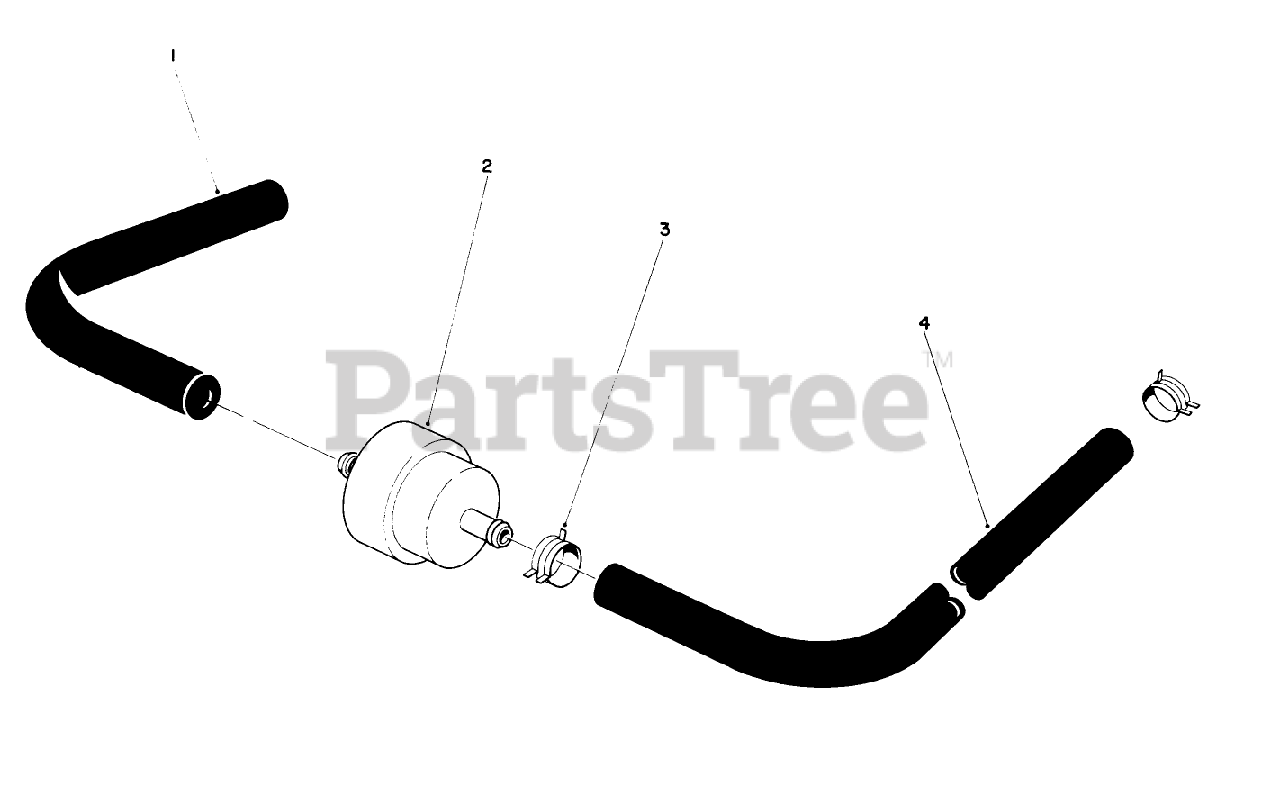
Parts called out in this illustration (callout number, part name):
1	Gas Line
2	FUEL FILTER
3	CLAMP-HOSE
4	Gas Line
